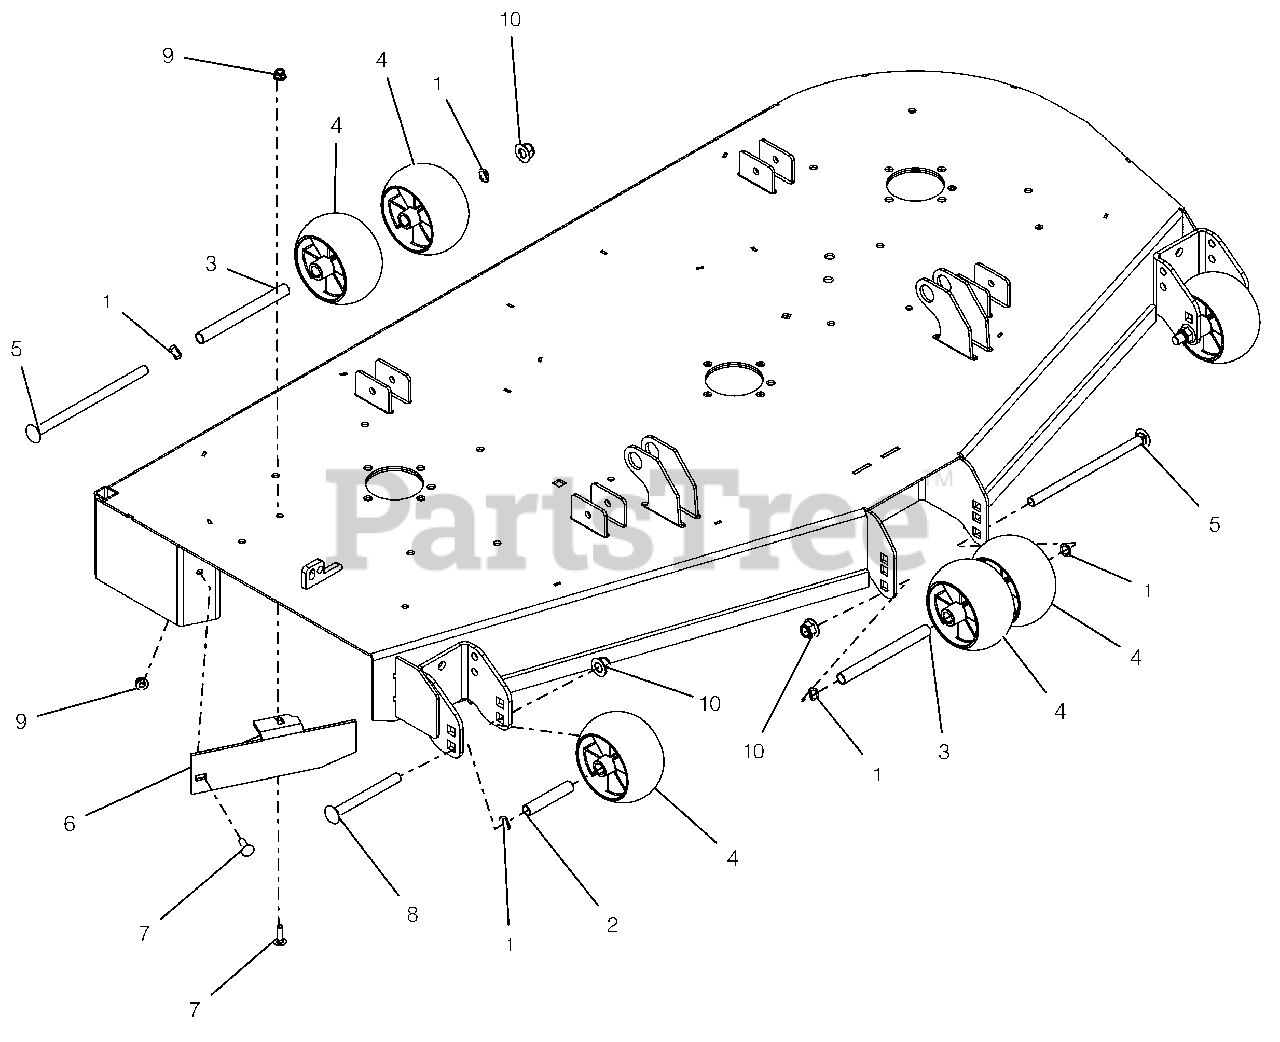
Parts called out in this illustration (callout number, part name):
1	WAVE WASHER .531X.781X.125FH
2	SPACER, .510X.625X3.35
3	SPACER, .510X.625X6.50
4	ANTI-SCALP WHEEL - 5X3 CTR
5	@BLT-RDHDSQNK .50-13X8.50 G5YZ
6	60" DISCHARGE BAFFLE - RED
7	@BLT-RDHDSQNK .31-18X1.00 G5YZ
8	BLT-RDHDSQNK .50-13X5.00 GR5YZ
9	@NUT-LK-NYL-FLG .31-18 YWZC
10	@NUT-LK-NYL-FLG .50-13 YWZC
